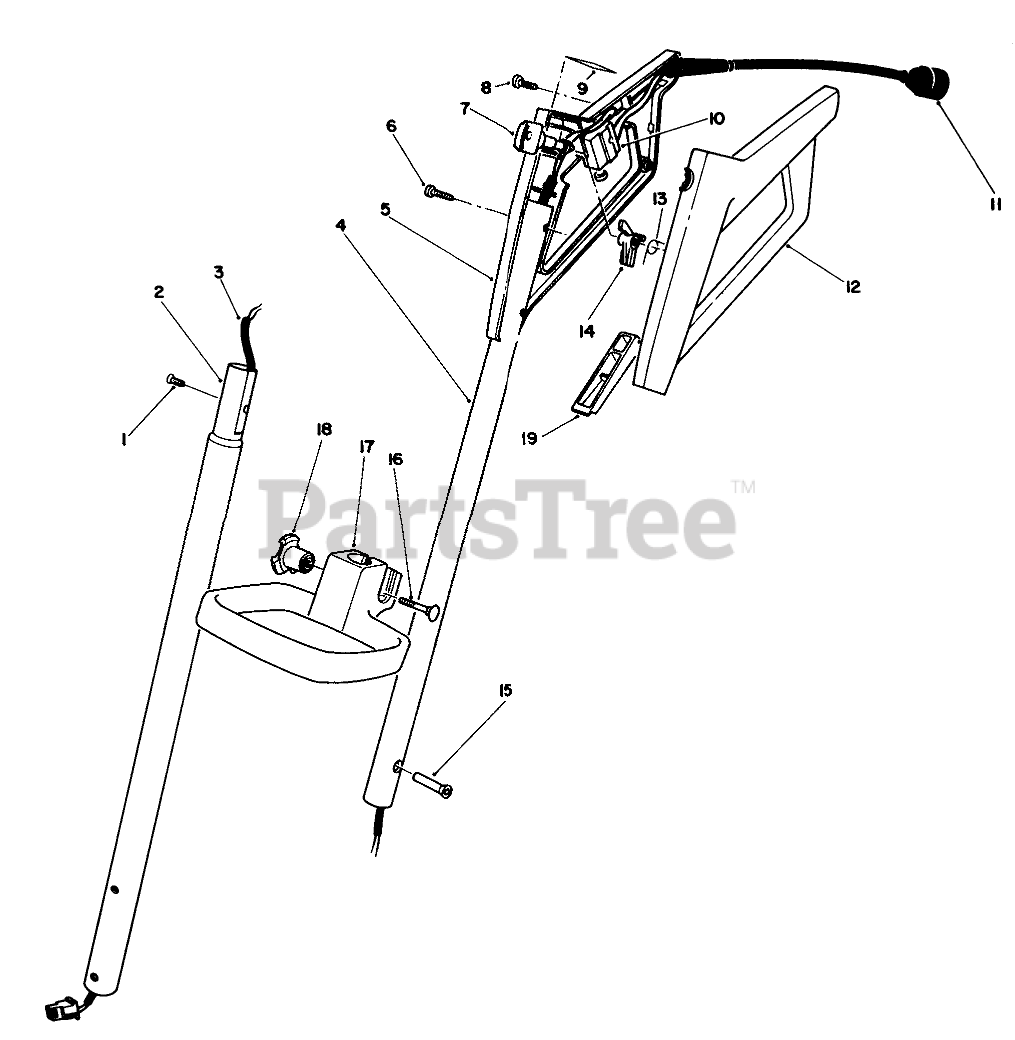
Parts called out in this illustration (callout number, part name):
1	FLAT HD SCREW #10-24X.5
2	LOWER TUBE P. SHOVEL
3	WIRE HARNESS, P.S.
4	UPPER TUBE P. SHOVEL
5	PS-CONTROL GRIP, RH
6	Screw
8	SCREW-PPH
9	UL GRIP DECAL
10	SWITCH-STARTER
11	SUPPLY CORD, 1200
12	PS-CONTROL GRIP, LH
13	TORSION SPRING
14	LOCKOUT
15	COUNTER SUNK NUT
16	BOLT-CARR
17	PS-ADJUST HANDLE-BLK
18	Knob
19	SWITCH BAR,POWER SHOVEL
